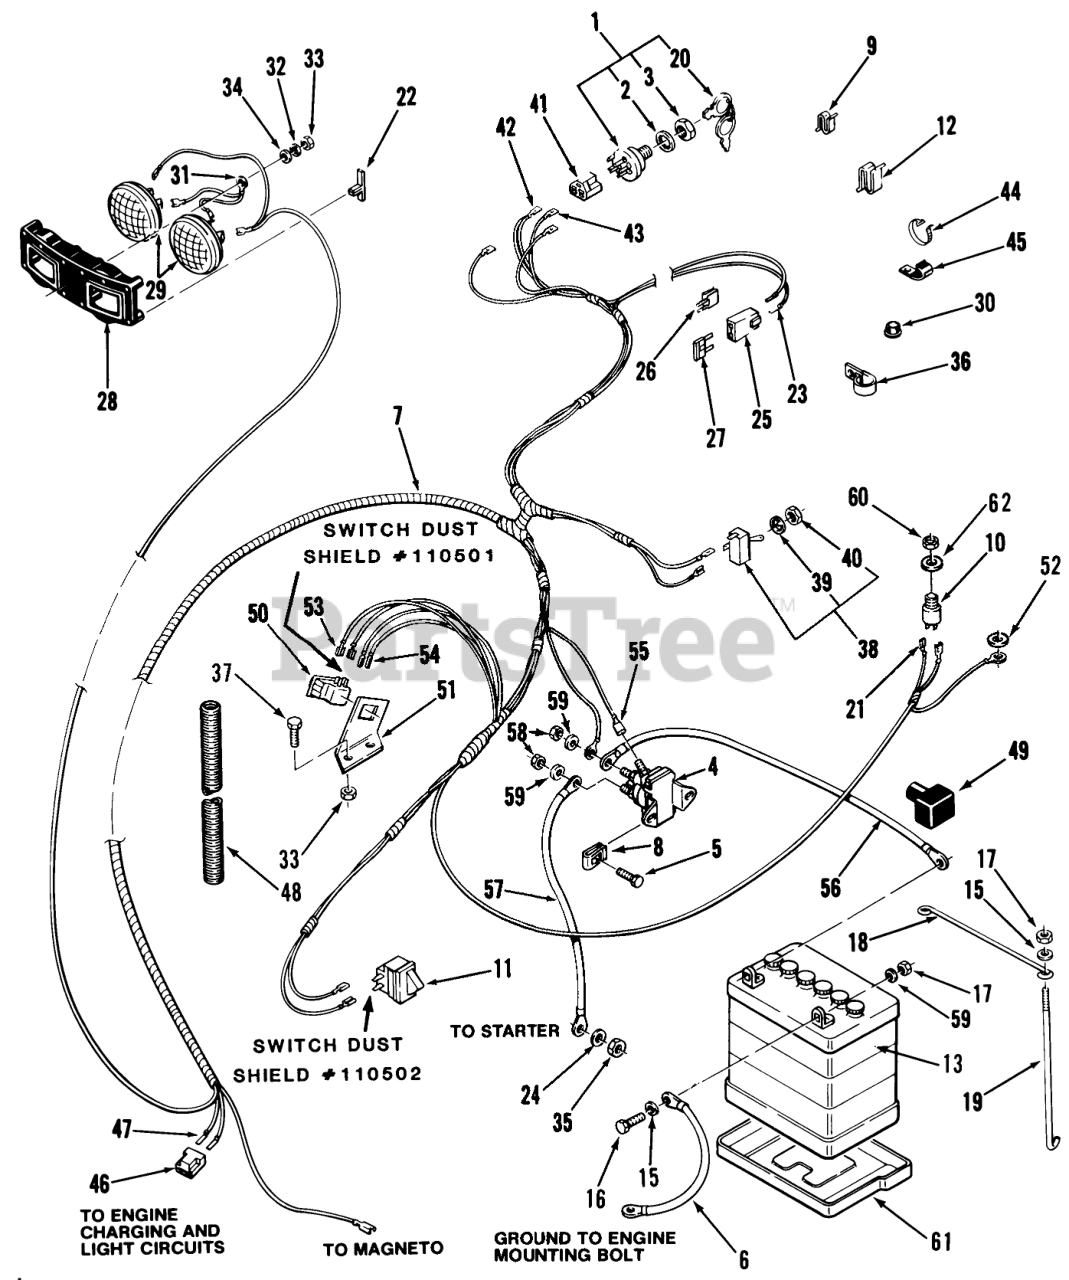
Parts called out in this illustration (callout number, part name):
1	ASSY-SWITCH IGNITION
2	LOCKWASHER
4	Solenoid
5	Screw
6	Wire
7	Wiring Harness Assy 216-5 Only
7	Wiring Harness Assy B-115 Only
8	Speed Nut
9	SPEED CLIP
10	SWITCH-SEAT
11	SWITCH INTERLOCK
12	CLIP-CABLE
13	Battery
16	Bolt
17	Nut
18	ROD-HOLD DOWN
20	Key-EL
21	Connector
22	CLIP-SPRING
23	TERMINAL-FUSE
24	Washer
25	AUTO-FUSEBLOCK TERM
27	FUSE-BLADE, 15 AMP
28	Headlight Retainer
29	HEADLAMP
30	BUSHING-NYLON .75
31	LIGHT GROUND WIRE
32	WASHER 5/16 SAE
33	Nut
34	Washer-Lock
35	Nut
36	CLAMP
37	Bolt
38	SWITCH-LIGHTS
39	TAB-WASHER
40	NUT-HEX
41	CONNECTOR-5 WAY-SERV
42	TERMINAL-TAB RCPT
43	Terminal
44	Cable Tie
45	CLIP
46	Conn Body Part of 7
47	Terminal
48	Conduit 216-5 Only
49	Boot
50	PTO Interlock Switch
51	BRACKET-SWITCH R
52	Washer-Lock
53	Terminal
54	Wire Terminal (Part of 1)
55	Terminal Part of 5
56	Wire
57	Starter To Solenoid Cable 16.0 in. (40.6 cm) 216-5 Only
57	Starter To Solenoid Cable 23.0 in. (58.4 cm) B-115 Only
58	Nut
59	Washer
60	NUT-HEX, SPECIAL
61	TRAY BATTERY
62	WASHER
